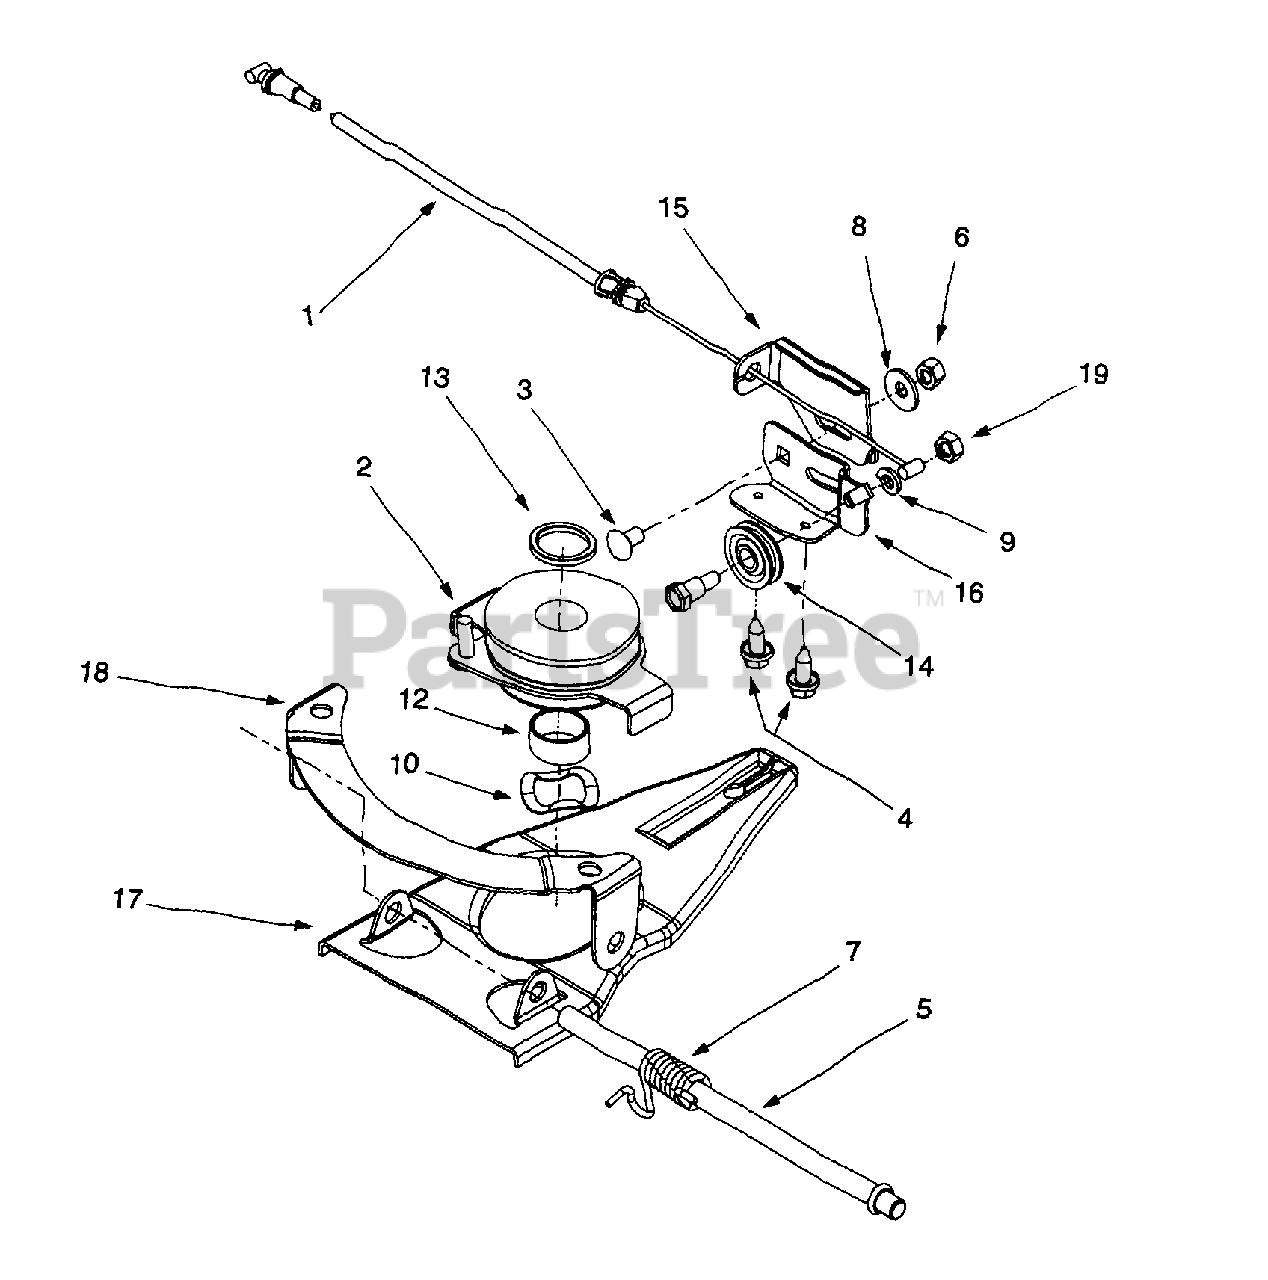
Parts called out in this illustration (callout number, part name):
1	Speed Selector Cable, 53"
2	Multi-speed Pulley Assembly
3	Carriage Bolt, 1/4-20 x .5
4	Self-tapping Screw, 1/4-20 x .625
5	Pivot Shaft
6	Nut, 1/4-20
7	LH Torsion Spring
8	Bell Washer, .265 x .75 x .062
9	Lock Washer, 1/4
10	Wave Washer, 1.38 x .68 x .029
12	Sleeve Spacer, .88 ID x 1 OD x .48
13	Sleeve Spacer, .88 ID x 1.13 OD x .12
14	Cable Roller
19	Hex Nut, 1/4-20
